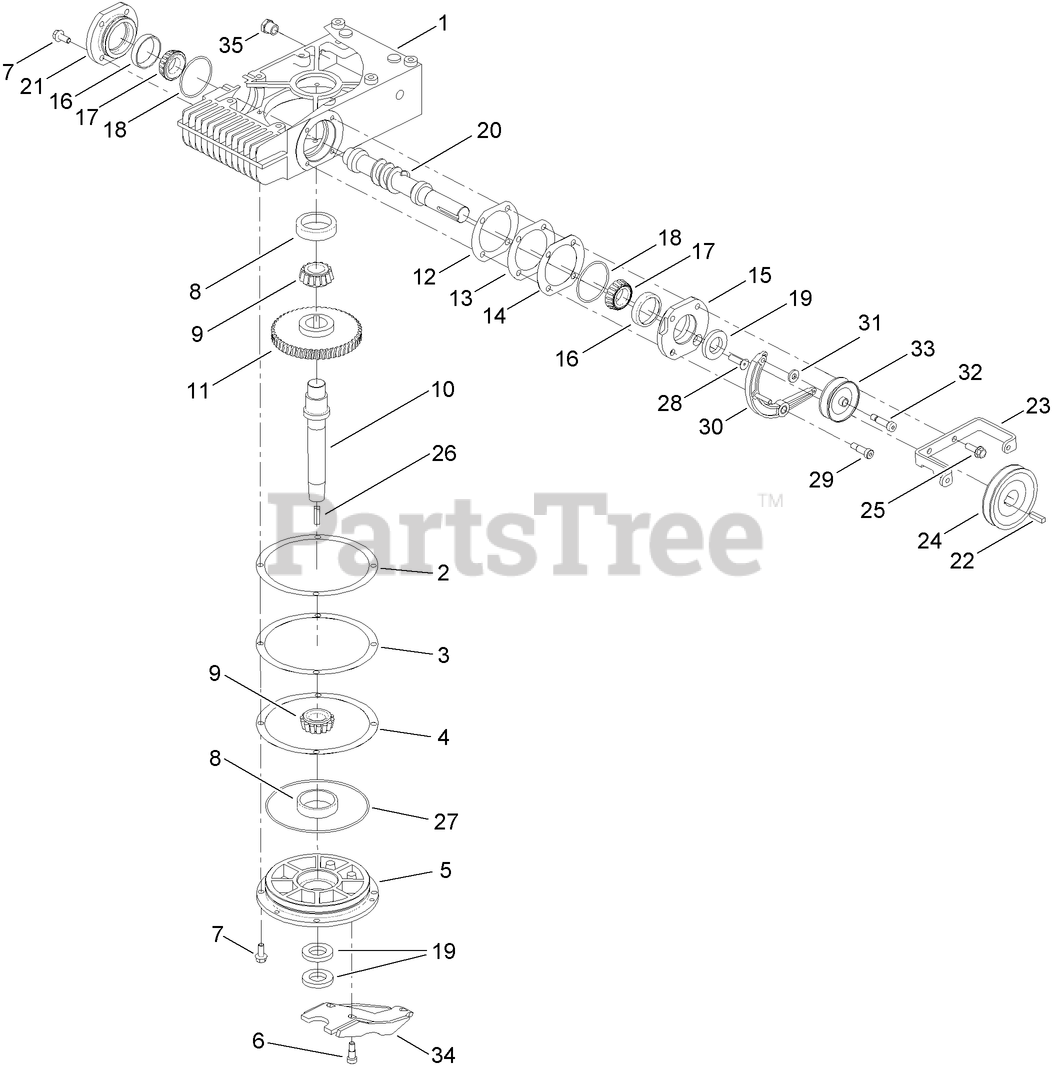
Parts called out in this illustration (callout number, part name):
1	GEARCASE
2	SHIM-COVER, BOTTOM (.001 INCH)
3	SHIM-COVER, BOTTOM (.005 INCH)
4	SHIM-COVER, BOTTOM (.010 INCH)
5	CAP-BEARING, BOTTOM
6	SCREW-HSBH
7	SCREW-HHF
8	BEARING-CUP
9	BEARING-CONE
10	SHAFT-OUTPUT
11	GEAR-WORM
12	SHIM-COVER, SIDE (.001 INCH)
13	SHIM-COVER, SIDE (.005 INCH)
14	SHIM-COVER, SIDE (.010 INCH)
15	COVER-BEARING, SHEAVE END
16	BEARING-CUP, TAPERED
17	BEARING-CONE, TAPERED
18	O-RING
19	SEAL-SHAFT
20	SHAFT-INPUT
21	COVER-BEARING, BLIND END
23	BRACKET-GUARD, BELT RED]
24	SHEAVE
25	SCREW-HHF
26	KEY-HARDENED
27	O-RING
28	SCREW
29	SCREW-SHOULDER, HSH
30	CLUTCH LEVER ASM
31	Washer
32	BOLT-SHOULDER
33	PULLEY-IDLER
34	LEVER-TILT
35	PLUG-SIGHT, OIL
